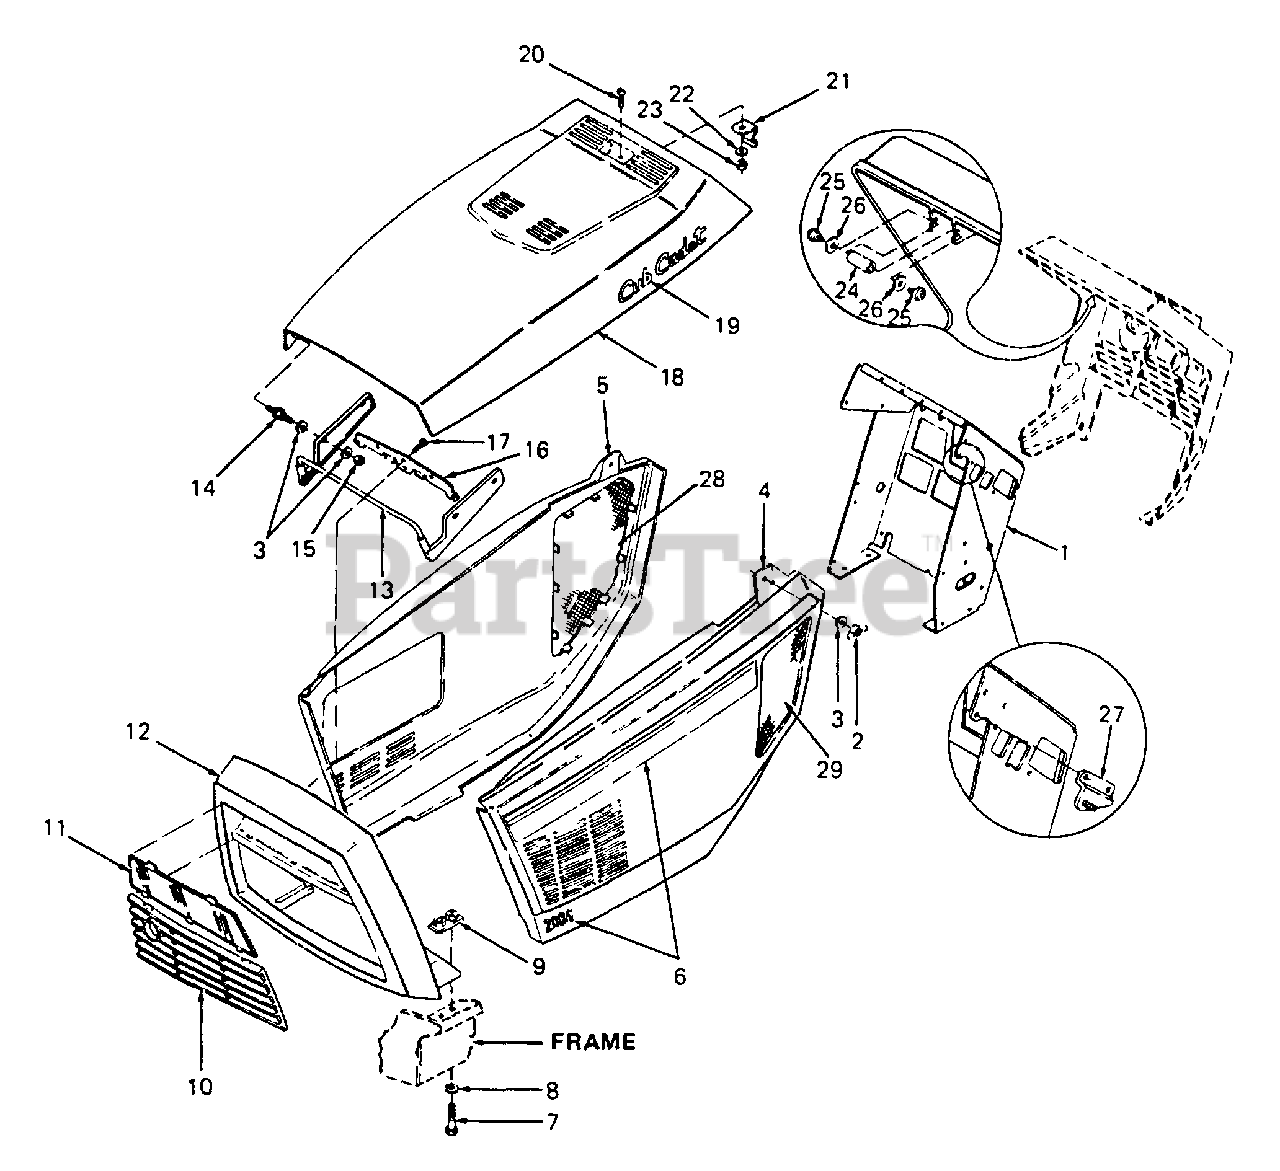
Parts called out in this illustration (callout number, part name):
3	Washer, Flat, .251 x .62 x .052 Thk
4	Panel, LH Side w/Slots
5	Panel, RH Side w/Cutout & Slots
6	Graphics Kit, LH Side Panel
7	Screw, Hex Cap, 5/16-18 x 1.0 Lg GR5
8	Washer, Lock, 5/16
9	Retainer, Grille Housing
10	Grille, Insert
11	Grille, Lens
12	Grille Hsg
15	Nut, Hex Patch Lock, 1/4-20
18	Hood
19	Graphic, Cub Cadet Script w/Studs
20	Screw, Truss Hd Mach, #8-32 x .38 Lg
21	Clip, Hood Latch
22	Washer, Flat, .16 x .38 x .045 Thk
23	Nut, Hex Keps, #8-32
24	Pin, Latch
25	Screw, Phillips Hd Truss Mach, 1/4-20 x .50 Lg
26	Washer, Flat, .285 x 1.25 x .060 Thk
